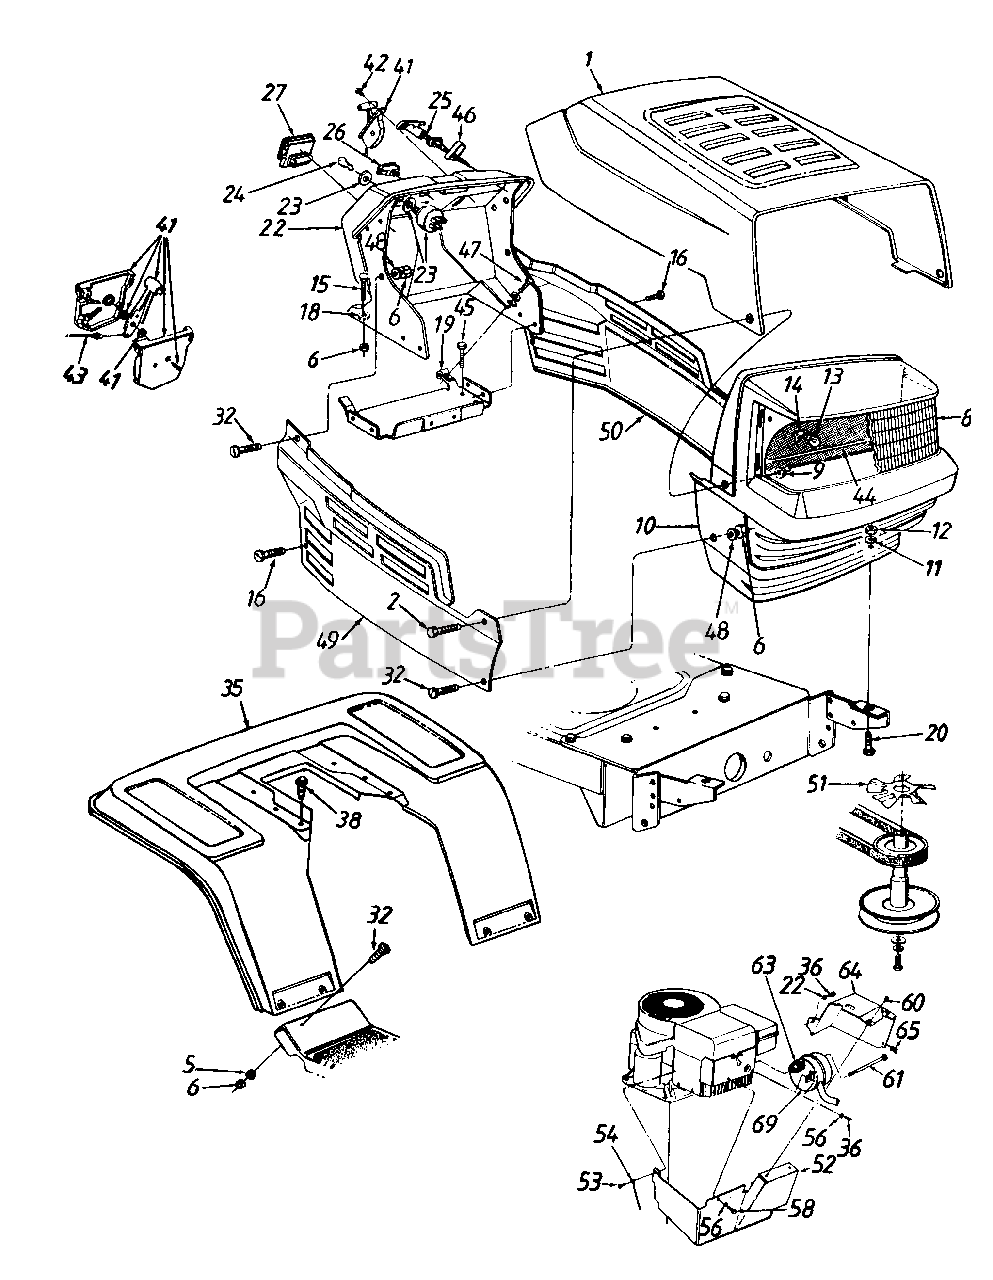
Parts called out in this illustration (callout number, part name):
6	Hex Nut 1/4-20 Thd.
8	Headlight Lens
9	Flange L-Nut 1/4-28 Thd.
10	Grille
11	Fl-Wash. .344" I.D. x 1" O.D.
12	Hex Nut 5/16-18 Thd.
13	Lamp
14	Socket
15	Carriage Bolt 1/4-20 x .75" Lg.
16	Hex Wash. Hd. TT-Tap Scr. 1/4-20 x .5" Lg.
18	Bolt Retainer 1/4" I.D.
19	Speed Nut 1/4-20 Thd.
20	Hex Bolt 5/16-18 x .75" Lg.
23	Ignition Switch
24	Ignition Key
25	Choke Control
26	Light Switch
27	Ammeter
32	Truss Mach. Scr. 1/4-20 x .5" Lg.
38	Hex Wash. Hd. AB-Tap Scr. 5/16 x .75" Lg.
41	Throttle Box Ass'y.
42	Truss Mach. AB-Tap Scr. #10 x .5" Lg.
43	Throttle Control Wire
44	Grille Reflector Label
45	Hex Wash. Hd. B-Tap Scr. 5/16-18 x .5" Lg.
46	Choke Retainer
47	Hex TT-Tap Scr. 1/4-20 x .75" Lg.
48	Bell-Wash. 1/4" I.D.
52	Muffler Heat Shield - Front
53	Truss Mach. Scr. 5/16-18 x .75" Lg
54	Ground Wire
56	Spr. Wash. 1/4" I.D.
58	Hex Bolt 1/4-20 x 3/8" Lg.
60	Hex B-Tap Scr. #10 x .38" Lg.
61	Shoulder Bolt
63	Exhaust Gasket
64	Muffler Heat Shield - L.H.
65	Speed Nut #10-24 Thd.
69	Muffler
